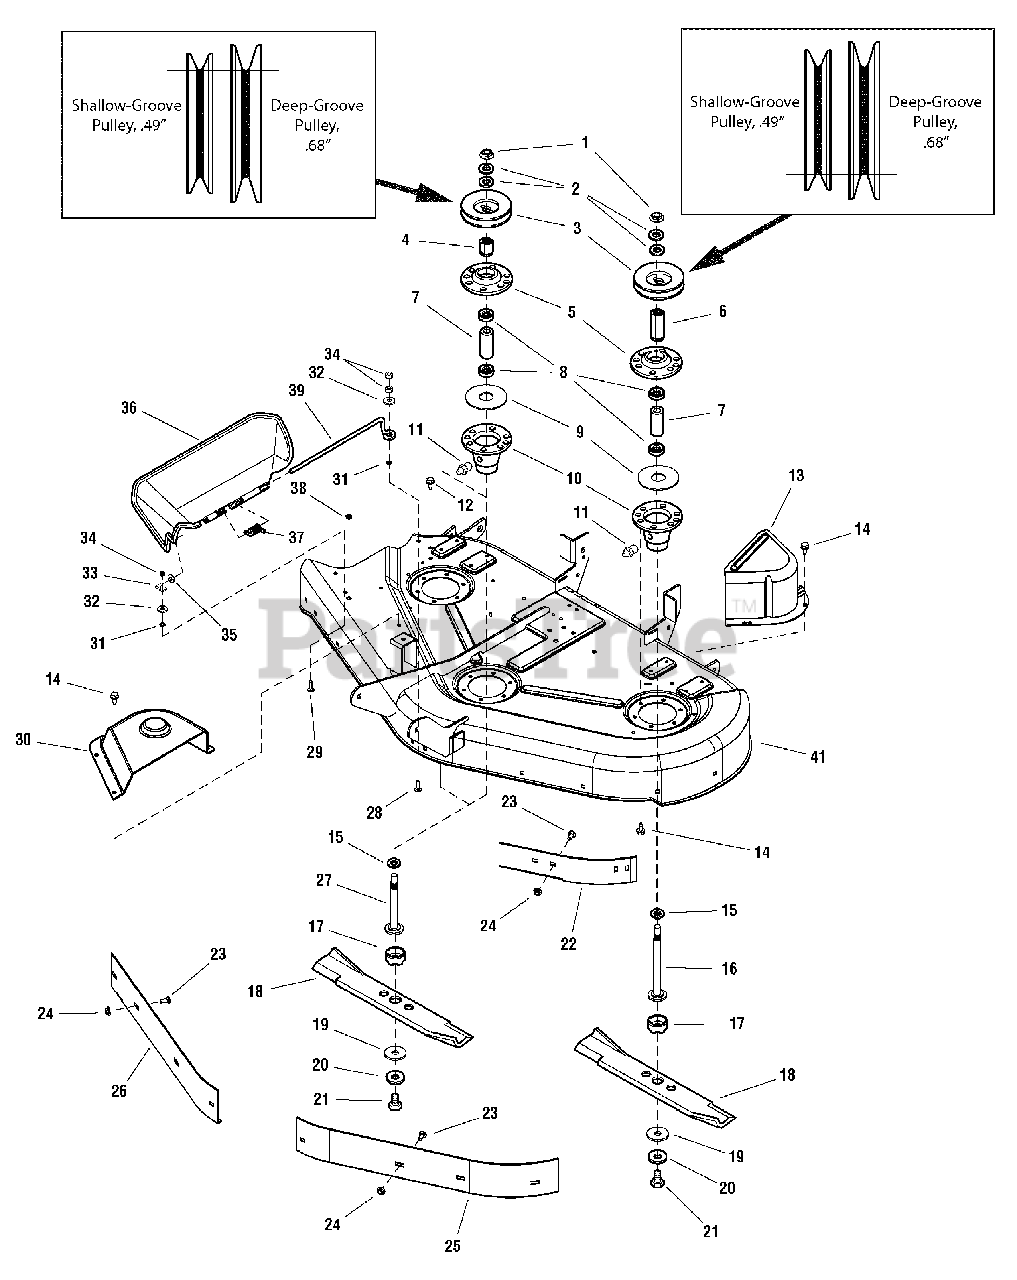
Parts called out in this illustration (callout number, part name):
1	NUT, Hex, Flange, 9/16-8
2	WASHER, Belleville
3	PULLEY, RH Arbor & LH Arbor, 4-1/2, .49" Shallow-Groove
3	PULLEY, RH Arbor & LH Arbor, 4-1/4, .49" Shallow-Groove
4	HUB, Pulley, RH
5	COVER, Arbor Housing
6	HUB, Adapter, LH
7	SPACER
8	BEARING
9	GASKET, Foam
10	HOUSING ASSEMBLY, Arbor Bottom, w/Lube Fitting
11	FITTING, Grease
12	CAPSCREW, Hex Head Washer Taptite, 3/8-16 x 3/4
13	COVER, Arbor
14	CAPSCREW, Hex Head, Taptite, 5/16-18 x 3/4
15	WASHER
16	SHAFT, Arbor
17	SHIELD, Grass, Lower
18	BLADE, Mower, 16-1/8
19	WASHER, Hex
20	WASHER, Spring
21	CAPSCREW, Hex Head, 7/16-14 x -1/4
22	BAFFLE, Anti-Blowout
23	BOLT, Carriage, 5/16-18 x 3/4
24	NUT, Hex, Flange Whizlock, 5/16-18
25	BAFFLE, Blowout LH, 44" Mower
26	BAFFLE, Blowout 44" Mower
27	SHAFT, Arbor, RH
28	CARRIAGE BOLT, 1/4-20 x 1-1/2, Black
29	CARRIAGE BOLT, 1/4-20 x 1, Black
29	CARRIAGE BOLT, 1/4-20 x 1-1/2, Black
30	COVER, Arbor, RH
31	NUT, Push On
32	WASHER, Plain, 1/4 (6 Total for Export)
33	CLAMP
34	NUT, Hex Lock ESNA, 1/4-20
35	WASHER, Flat, 5/16
36	DEFLECTOR, Plastic
37	SPRING
38	PLUG, Button for .344 Square Hole
39	ROD, Deflector, Front
41	HOUSING ASSEMBLY, 44" Mower Frame Hung (Orange)
41	HOUSING ASSEMBLY, 44" Mower Ground Following (Red)
